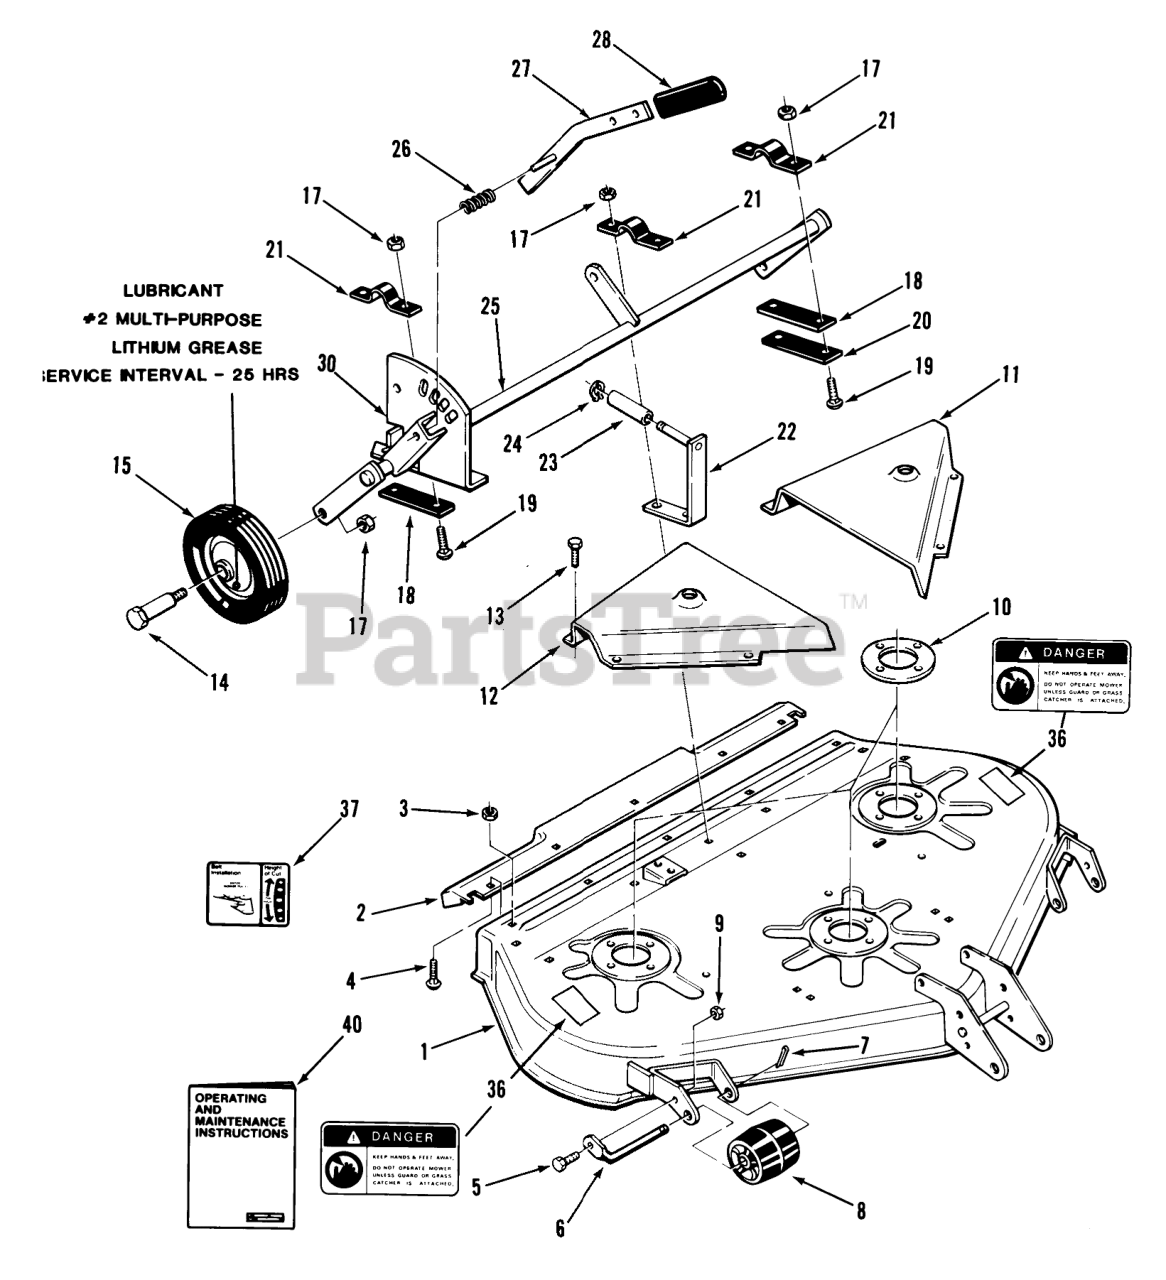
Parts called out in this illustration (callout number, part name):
1	ASSY 42" MOWER RE R
2	EXTENSION R
3	Nut
4	Bolt
5	H H C S
6	ROLLER-SHAFT
7	Cotter Pin
8	Roller
9	Nut
10	PLATE-SPINDLE
11	Belt Cover LH
12	Belt Cover RH
13	Bolt
14	BOLT-SHOULDER
15	WHEEL
17	Nut
18	STRAP 1/16 B
19	Bolt
20	Bar
22	Bracket Guide
23	SPACER
24	Snap Ring
25	Gage Wheel Support
26	SPRING-COMPRESSION
27	Lever
30	QUADRANT R
36	Danger Decal
37	DECAL-HEIGHT BELT
40	Operating & Maintenance Instructions
